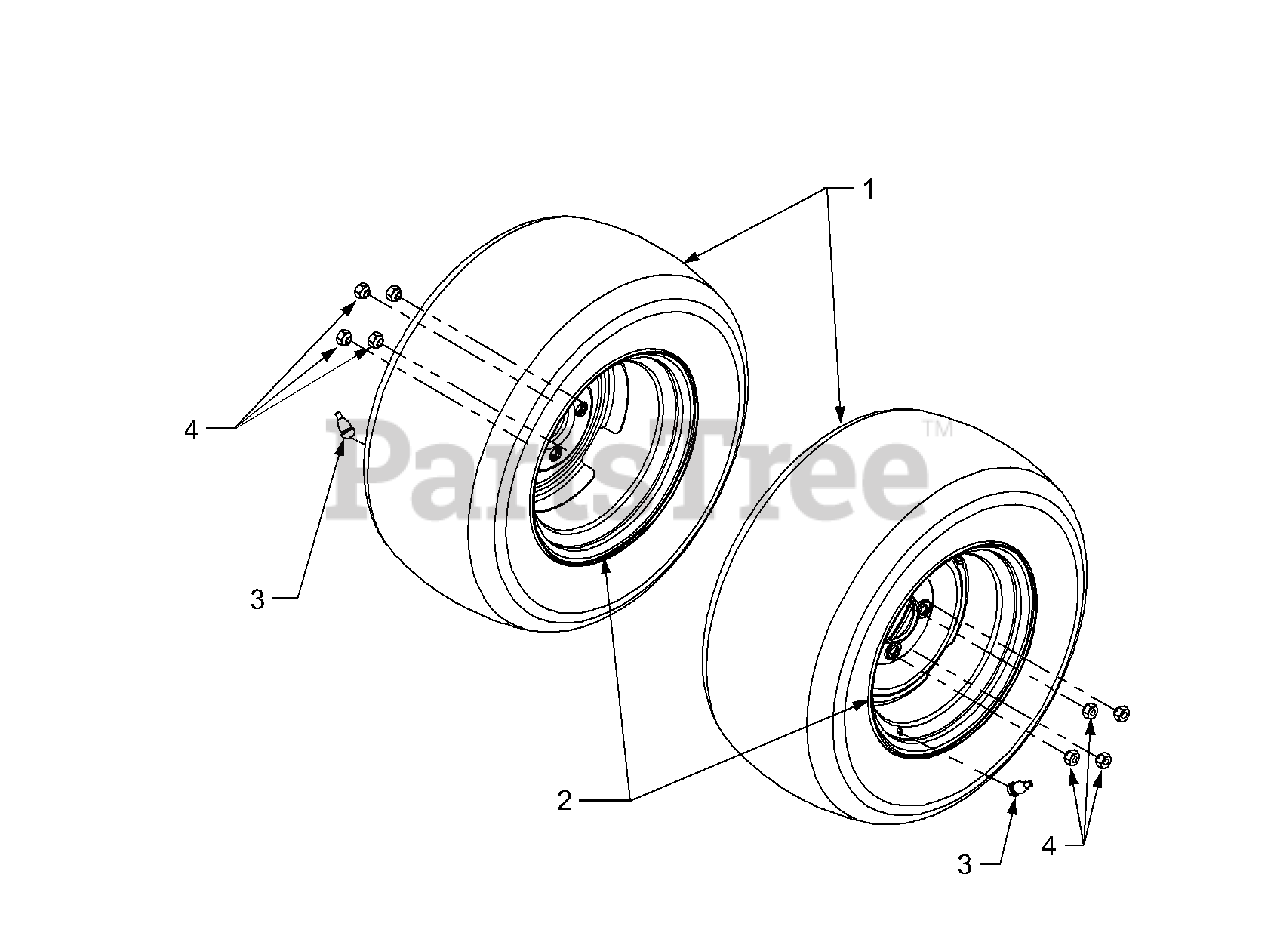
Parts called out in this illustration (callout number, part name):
1	Tire, Turf, 23 x 9.5 - 12
2	Rim Assembly, Wheel
3	Valve, Tubeless Air
4	Lug Nut, 7/16-14
